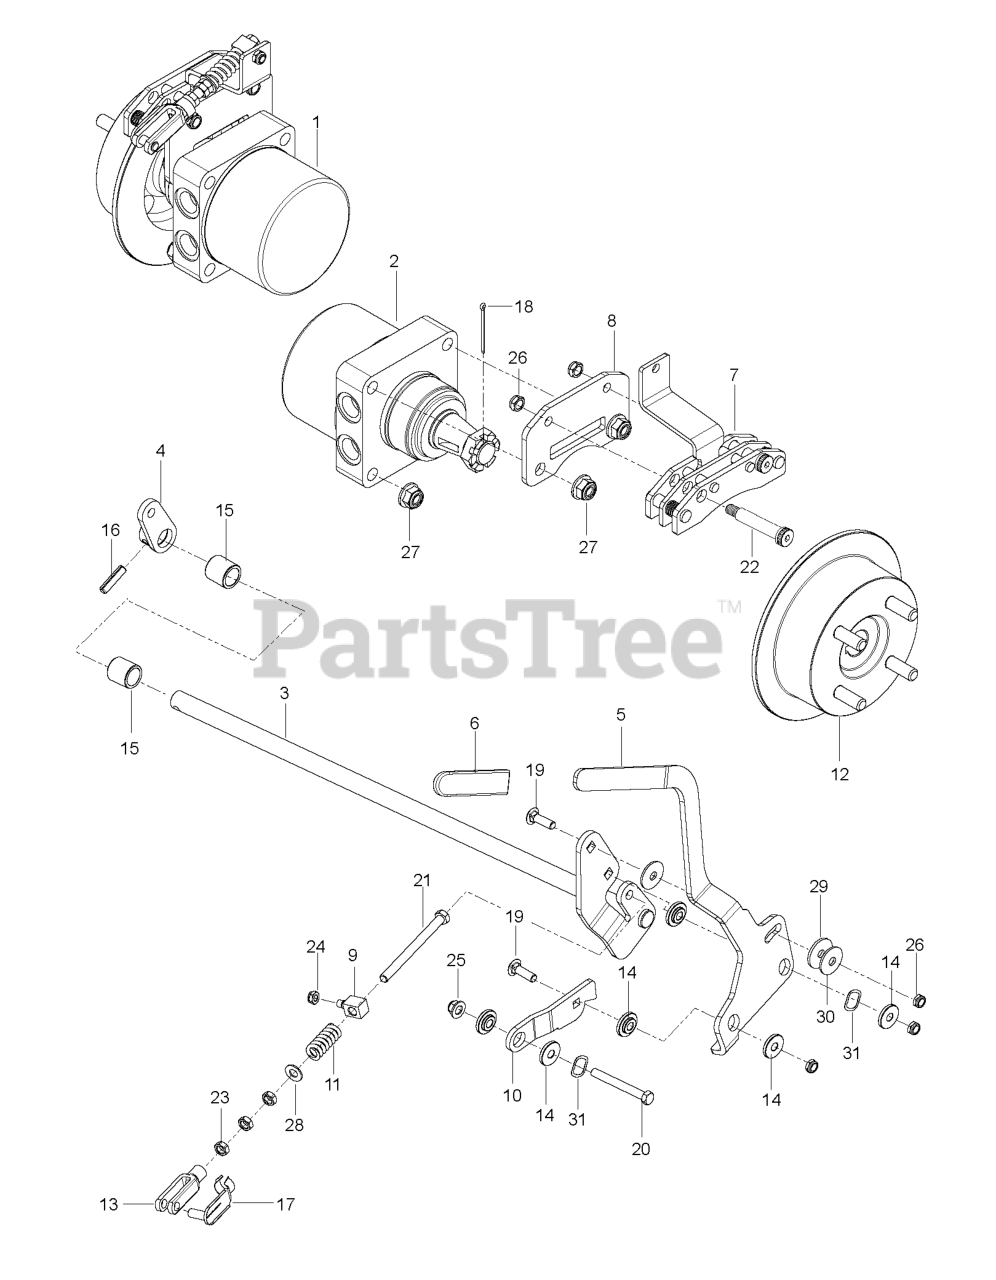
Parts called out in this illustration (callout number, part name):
1	MOTOR, TL0310, RT
2	MOTOR, TL0310, LT
3	SHAFT, BRAKE WLDMT
4	ARM, RT BRAKE
5	LEVER.BRAKE.BLACK
8	PLATE, CALIPER
9	SWIVEL, BRAKE
10	LINK, FOLLOWER
12	HUB, DISC BRAKE, W/STUDS
13	YOKE-3/8-24 PLTD
14	BUSHING, BRAKE
15	BUSHING, SLEEVE 3/4 X 1.0
16	5/16 DIA ROLL PIN
17	PIN, CLEVIS SPRING, 3/8
18	COTTER PIN 1/8 X 2
19	BOLT.3/8-14X1.25
20	HCS 3/8-16 X 3-1/4 GR5 ZD
21	HCS 3/8F X SPECIAL
22	BOLT, SHOULDER, 1/2 X 2.25
23	NUT 3/8-24 JAM
24	5/16-18 THIN PROF NY
25	NUT 3/8-16 HEX FLG NYLOC ZD
26	NUT HEX 3/8-16 NYLON, THIN
27	NUT, 1/2-13 HEX FLG NYLOC ZD
29	WASHER, FRICTION, 1/8
30	CONE WASHER
31	WASHER, .825 X 1.087, WAVE
